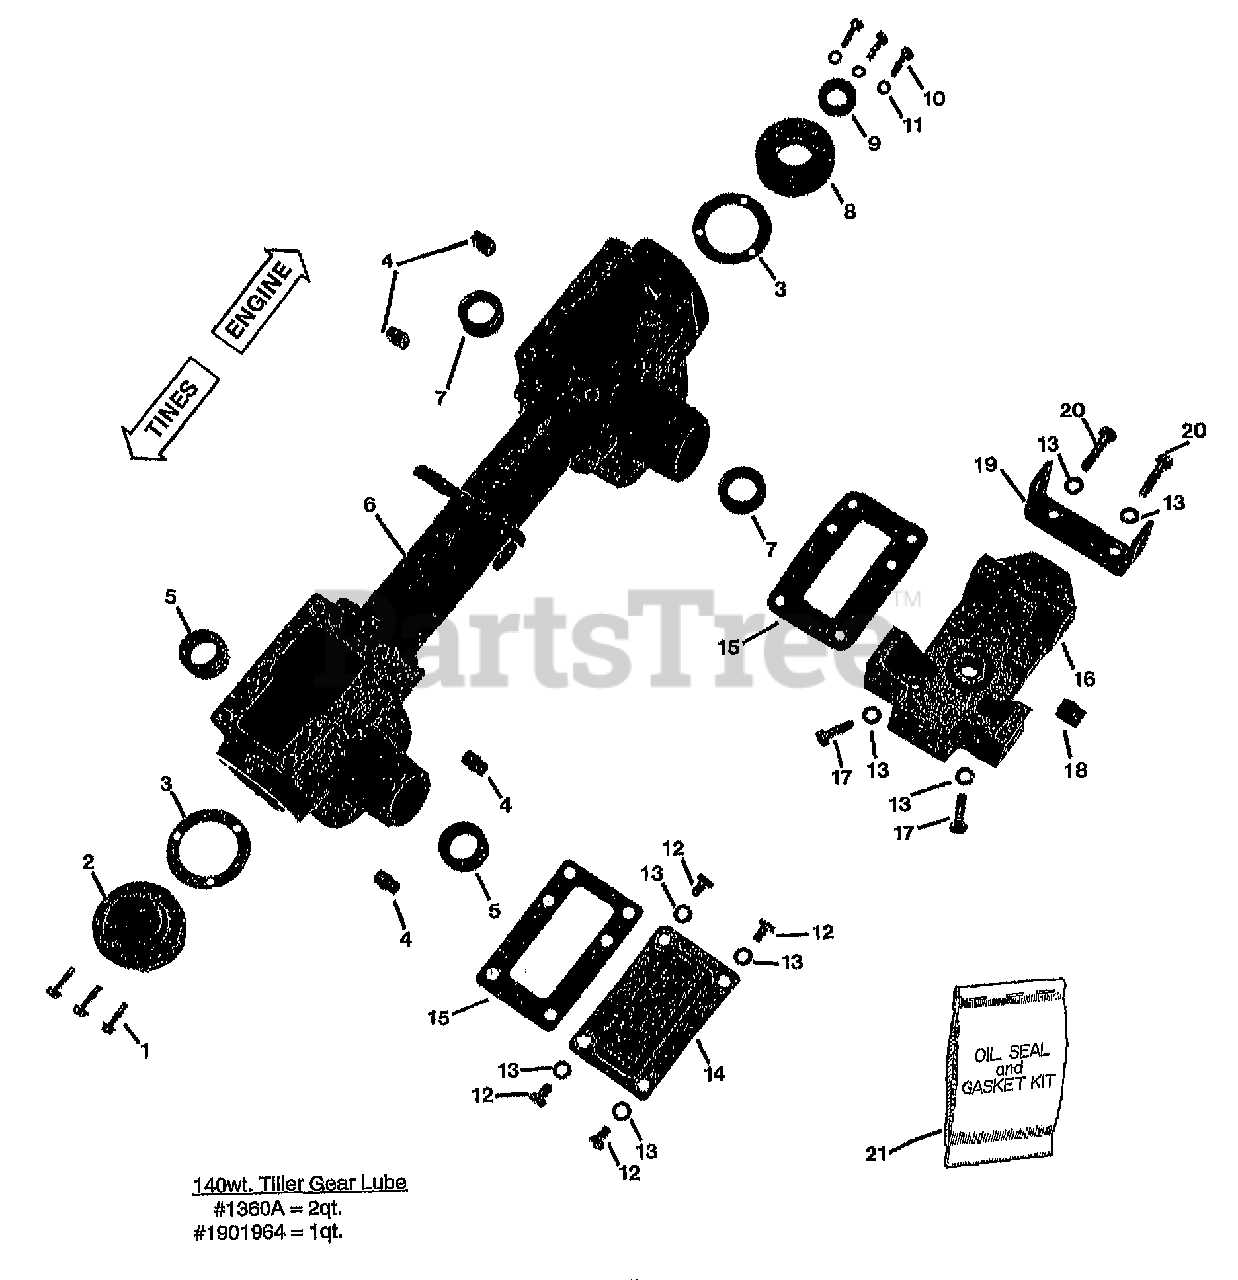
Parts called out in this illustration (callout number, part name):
1	SCR-HFLK 1/2-20X.875 (Rear bearing cap mounting)
2	CAP-REAR #1115 (Rear Bearing)
3	GASKET-BRG COVER (Front and rear bearing caps 0.010" thick)
4	PLUG-PIPE 1/4 NPT (Gear oil level check and gear oil drain holes, front & rear)
5	SEAL-OIL TRIPLE LIP (Tiller shaft, LT & RT side)
6	ASSM-TRANS A UNIT (W/O covers, shaft, gears, seals, etc.)
7	SEAL-OIL WHEEL SHAFT (Lt & Rt sides)
8	CAP (Front Bearing)
9	SEAL-PINION SHAFT PT/85030/00 (Main Drive shaft, front)
10	SCR-HH 1/4-20X.75 G5 ZP (Front bearing cap mounting)
11	WASHER-LK .25 ZP
12	SCR-HH 5/16-18X.5 GD5 YEL (Tiller housing cover to case)
13	WASHER-LK .312 ZP (Used in both covers)
14	CVR-TRANS REAR PNT (Tiller Housing)
15	GASKET-GEAR HSG (Transmission covers, front & rear)
16	COVER-TRANS MACH (Front Transmission)
17	SCR-HH 5/16-18X1.0 G5 ZP (Front Transmission to cover)
18	PLUG-PIPE 3/8 NPT (Gear oil fill hole)
19	BRKT-HANDLEBAR PIVOT (Handlebar attachment)
20	SCR-HH 5/16-18X1.25 G5 (Handlebar attachment)
21	SEAL & GASKET SET-JR (Inc. 2 #3, 2 #15, 2 #5, 1 #9)
